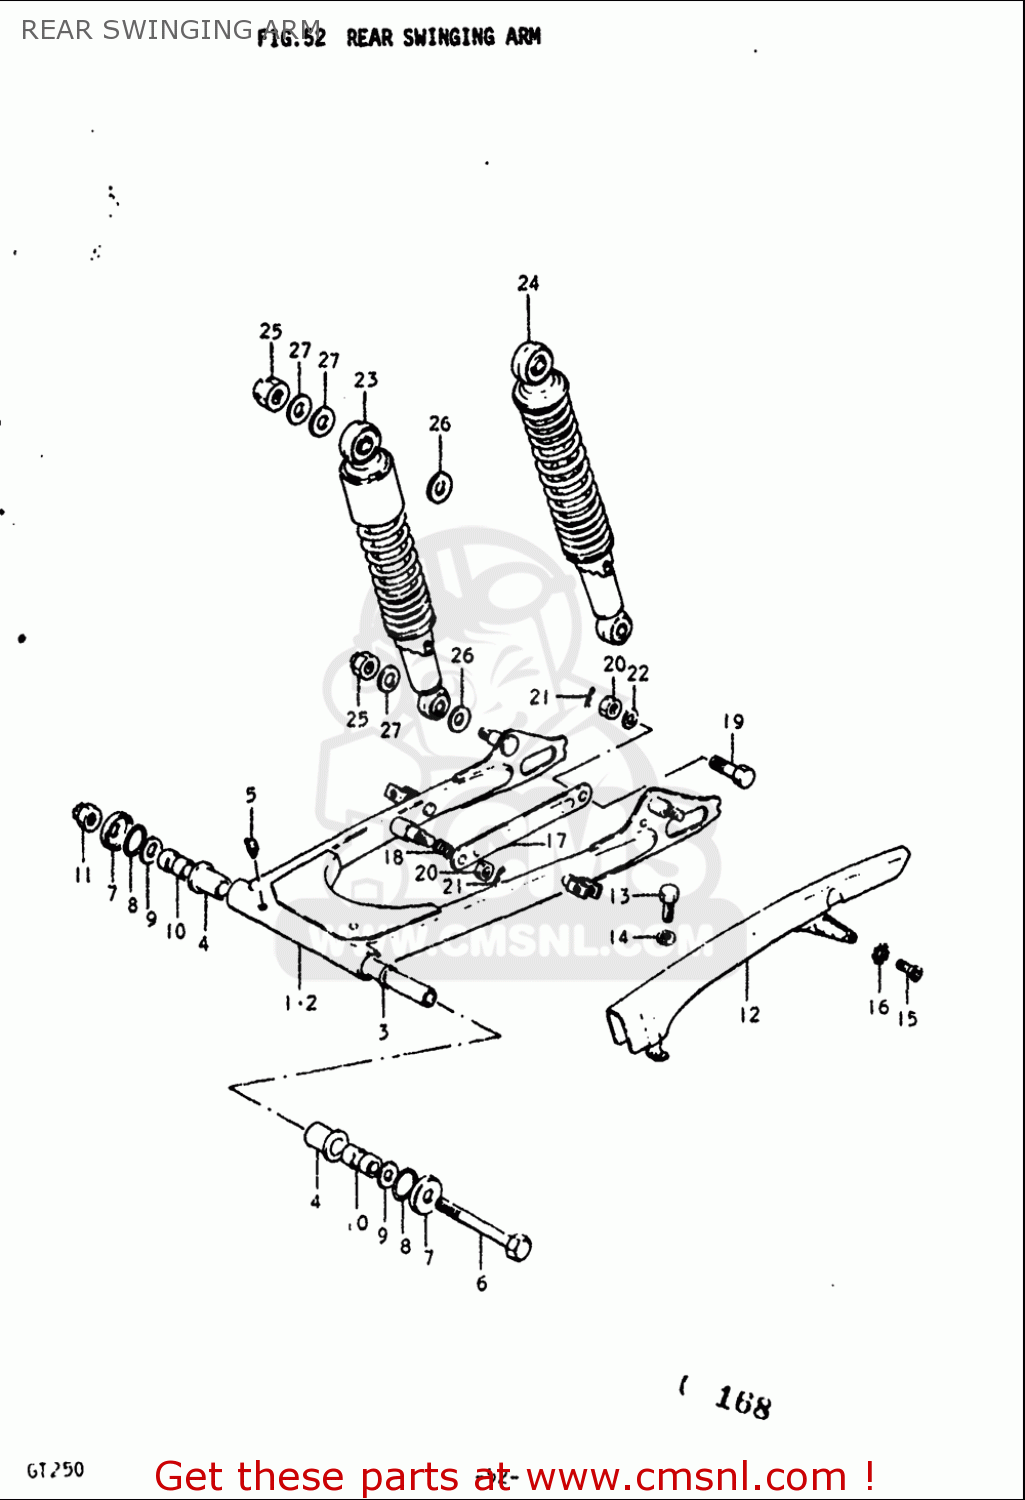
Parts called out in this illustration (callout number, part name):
4	BUSH
5	NIPPLE,GREASE
7	COVER
8	O RING(D:3,ID:29.5)
9	WASHER(14.5X29X2.3)
10	SPACER
13	BOLT
14	WASHER,LOCK
15	SCREW(5X12)
16	TOOTHED WASHER
18	SPRING
19	BOLT(10X31)
20	NUT
21	CLIP
22	WASHER,LOCK
25	NUT
26	WASHER
27	WASHER (10.5X24X2.3)
